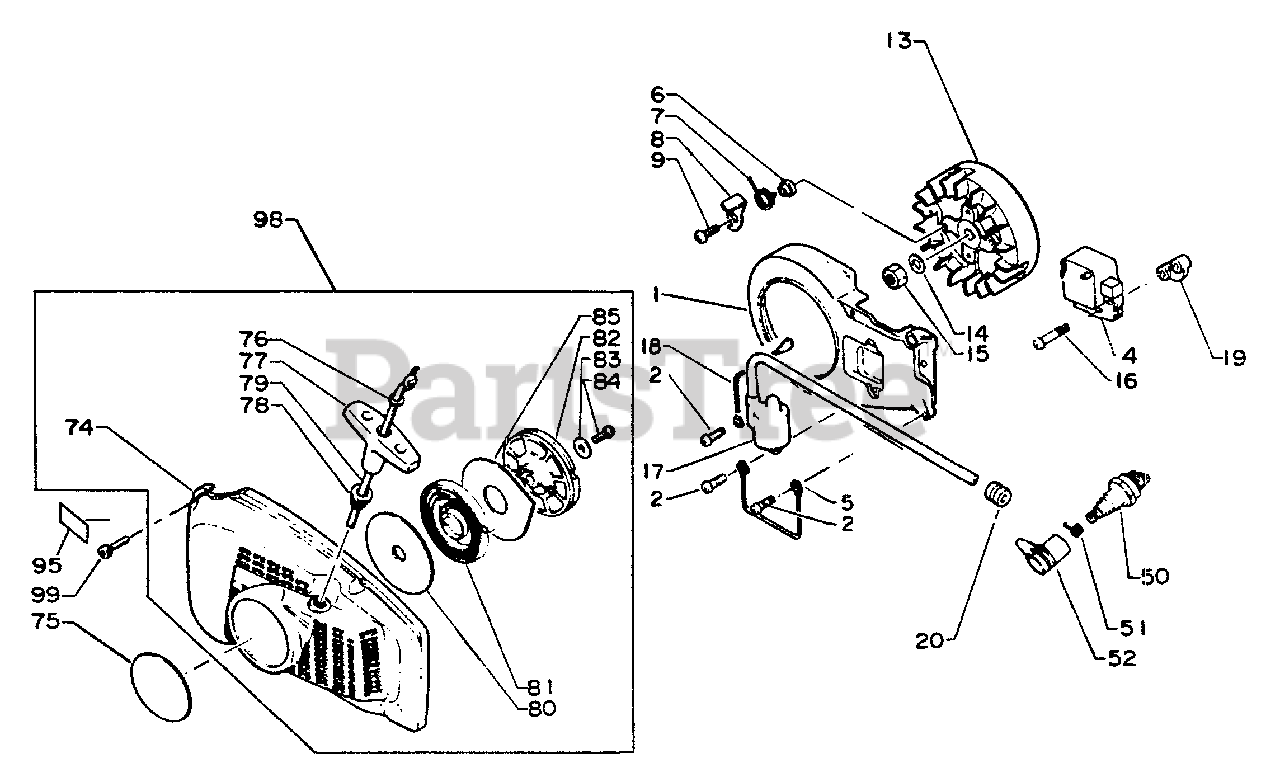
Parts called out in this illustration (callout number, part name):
1	COVER, FAN
2	SCREW 4×16
4	COIL, IGNITION
5	LEAD - GROUND
7	SPRING, RETURN
8	PAWL, STARTER
9	SCREW
13	FLYWHEEL
16	BOLT 5×28
17	COIL, IGNITION
18	LEAD
50	SPARK PLUG - BPM7A
51	TERMINAL, SPARK PLUG
52	CAP, SPARK PLUG
74	CASE, STARTER
75	LABEL - ECHO
78	GUIDE, ROPE
79	ROPE, STARTER 3.5×850
80	PLATE, SIDE
81	SPRING, RECOIL
82	REEL, ROPE
83	WASHER 5.2×16×1.0
84	SCREW 5×10
85	PLATE, SIDE
95	LABEL - NOISE
98	STARTER ASSY
99	BOLT 5×20
